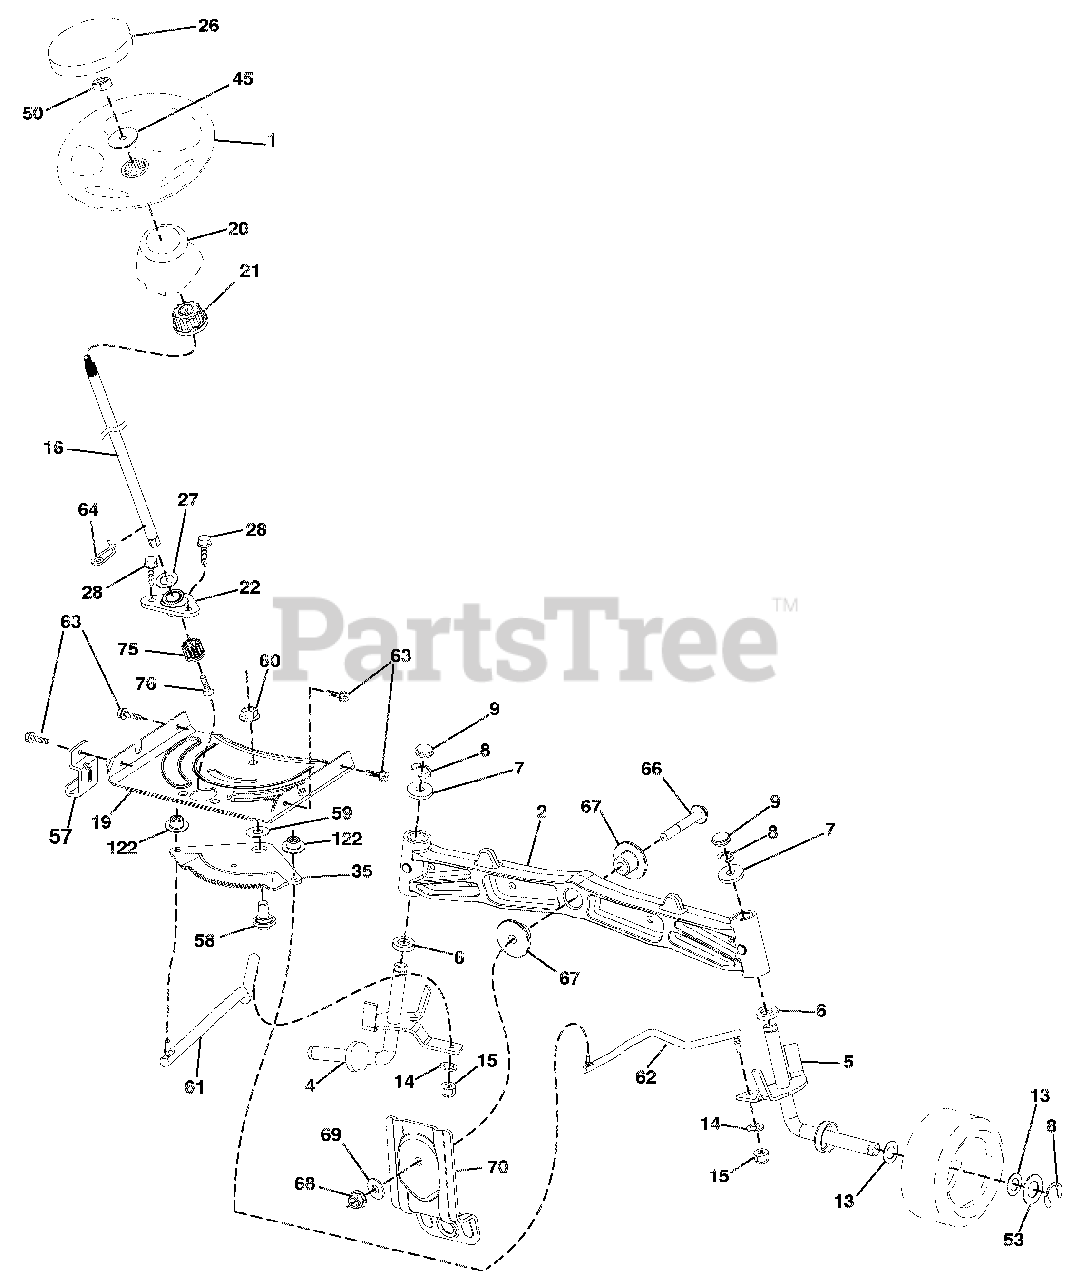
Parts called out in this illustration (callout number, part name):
1	WHEEL STEERING
2	AXLE.CAST IRON
4	SPINDLE.WELDED.LH.15"TEX
5	SPINDLE.WELDED.RH.15"TEX
6	WAHSER THRUST .75 X 1.230
7	WASHER.25/32 X 1-5/8 X 16GA.
8	RING.KLIP.#T5304-75
9	CAP.SPINDLE.FR.TOP.BLK.
13	WASHER.25/32 X 1 1/4 X 16 GA.
14	Washer, Lock 3/8
15	NUT.CROWNLOCK.3/8-24
16	SHAFT STEER
19	PLATE.STEER.DDL.NLT/NGT
20	BOOT.STEERING
21	ADAPTER.STEER
22	STEER.SUPT. LOWER
26	CAP WHEEL STEERING HRS/SRS BLK
27	WASHER 21/32 X 1 X 1 GA.
28	SCREW.HEXWSH THDR3/8-16X3/4.BL
35	GEAR SECTOR.PLATE.DDL.NLT/NGT
50	Nut, Hex, Flangelock 3/8-16
53	WASHER.HARDEN..793 X 1.637X060
57	BRACKET.UPSTOP.GT/LT.TEX
58	BOLT.SHOULDER.SECTOR.PIVOT.CFM
59	WASHER.THRUST.SECTOR.STEER.NLT
60	NUT.FLANGE LOCK.5/8-11
61	DRAGLINK.LH.BALLSTUD.DDL.
62	DRAGLINK.RH.BALLSTUD.DDL
63	SCREW.5/16-18X3/4.SMGML.TAP/BL
64	RETAINER.CLIP.SPRING.STEERING
66	BOLT.HEX.FGHD.7/16-14 X 3.SERR
67	BUSHING.PM.FRONT AXLE
68	NUT.LOCK.FLANGE.7/16-14.GR5
69	WASHER.1.5 X .505 X .118
70	BRACKET.DECK.SUSPENSION.FRONT
122	CAP GEAR SECTOR
